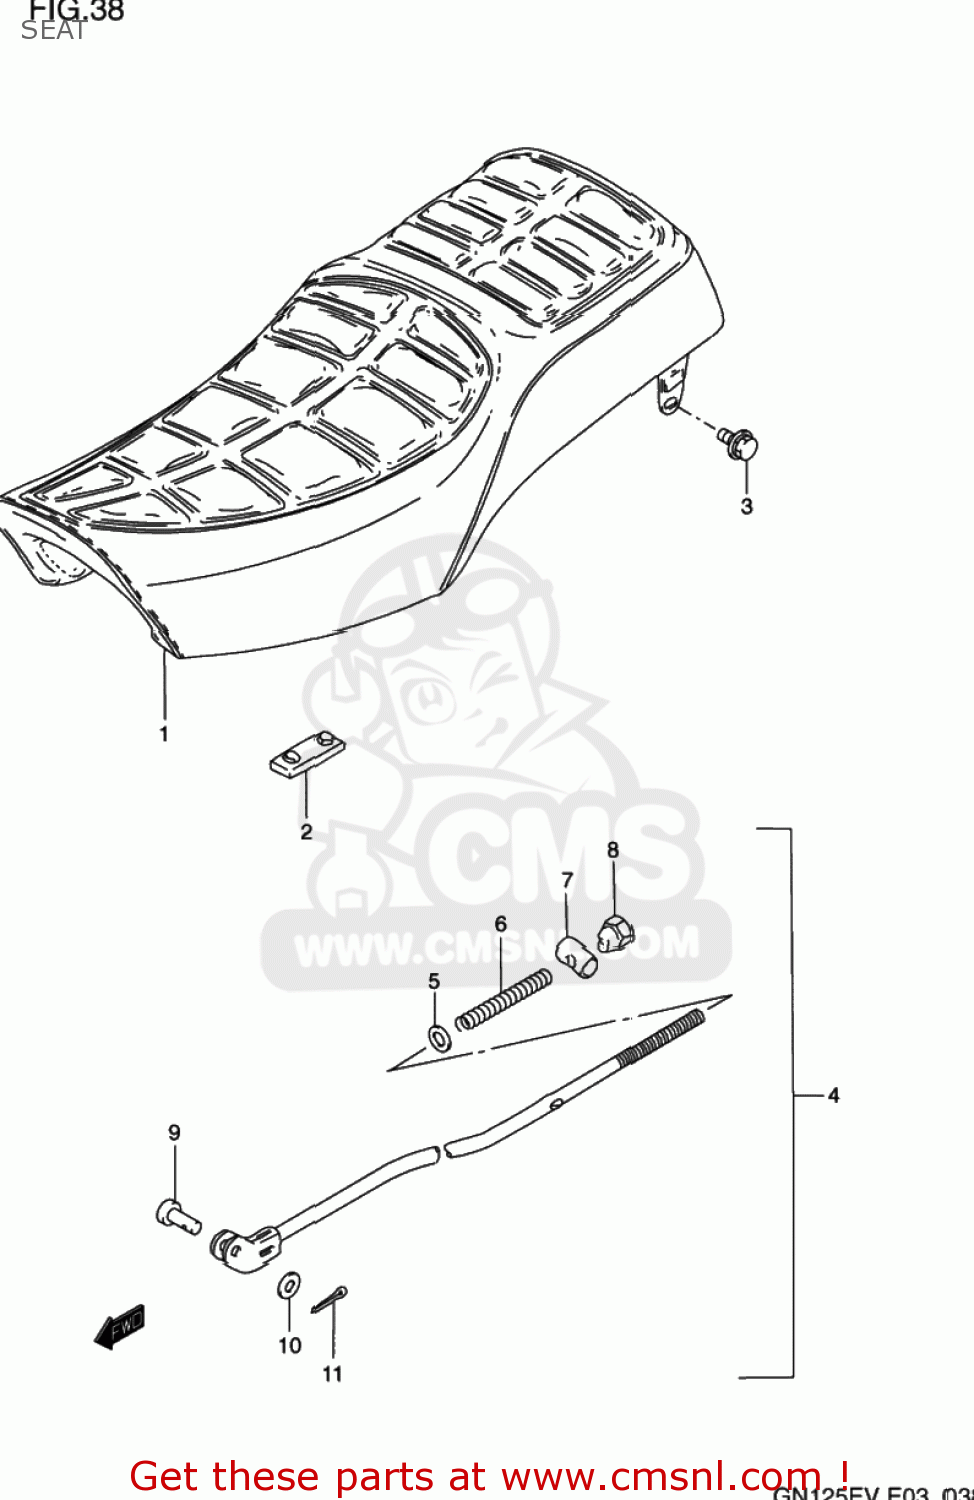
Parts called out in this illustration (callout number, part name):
1	SEAT ASSY
2	CUSHION
3	BOLT
4	ROD ASSY,RR BRAKE
5	WASHER
6	SPRING
7	PIN(11X18)
8	NUT
9	PIN(L:13.5)
10	WASHER
11	PIN 20X20
